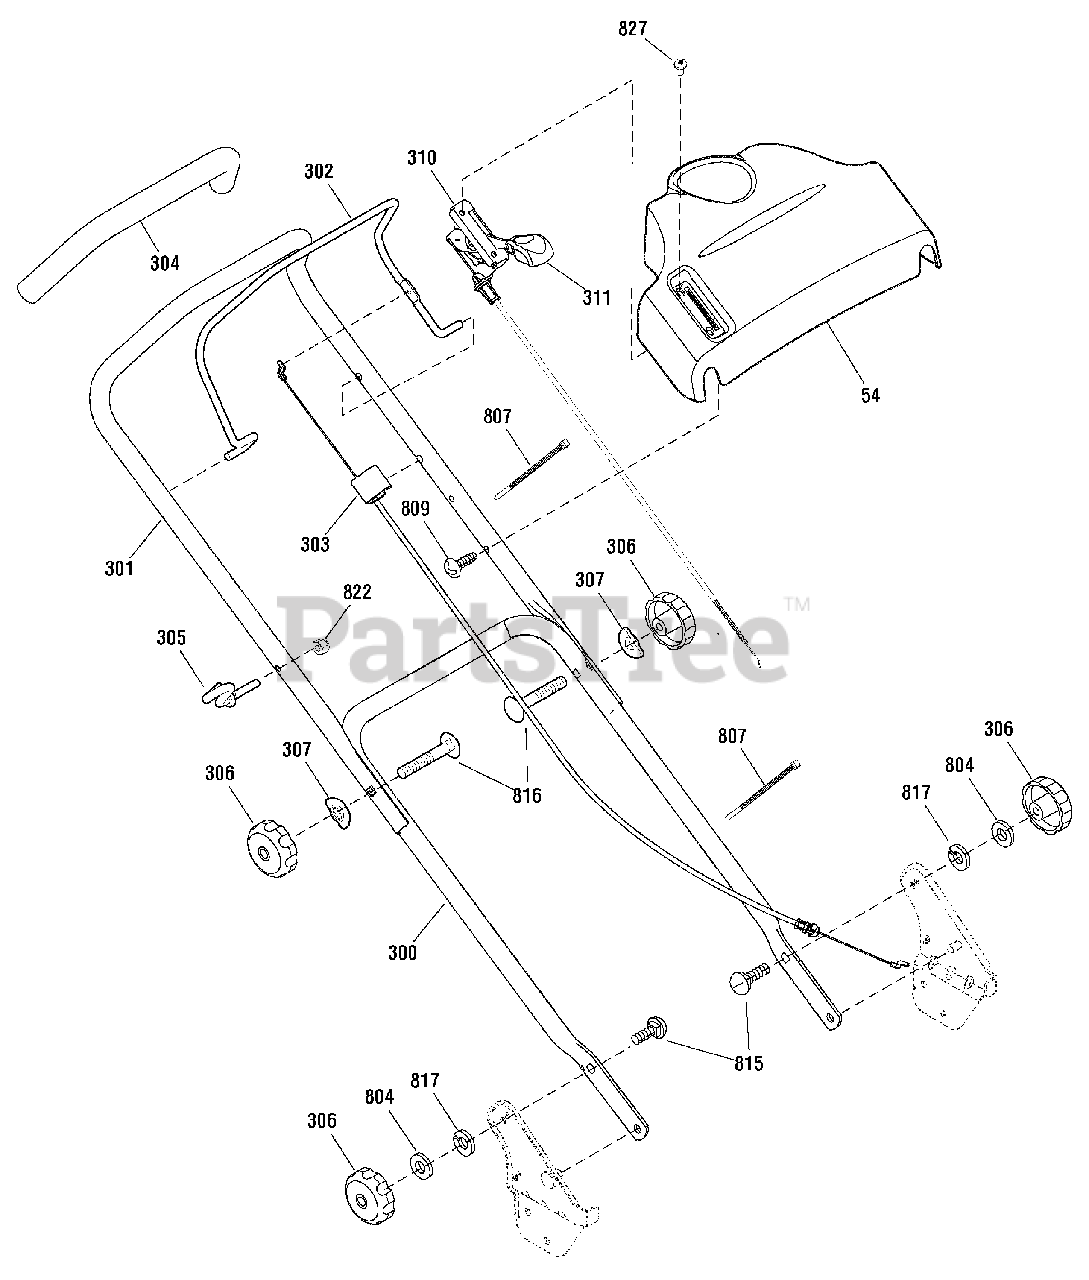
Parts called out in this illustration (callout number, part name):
54	CONTROL PANEL
300	HANDLE, Lower
301	HANDLE, Upper
302	LEVER, Engine Stop
303	CABLE, Engine Stop
304	TUBING, Foam
305	GUIDE, Rope
306	KNOB, Adjuster
307	WASHER, Formed
310	THROTTLE CONTROL
311	KNOB, Throttle Control
804	WASHER, 5/8
807	CABLE TIE
809	SCREW, Self Tap, #10-16 x 1/2
815	BOLT, Carriage, 5/16-18 x 1-1/8
816	BOLT, Carriage, 5/16-18 x 2
817	Washer, Lock
822	NUT, Hex, 1/4-20
827	SCREW, 1/4-20 x 7/8
